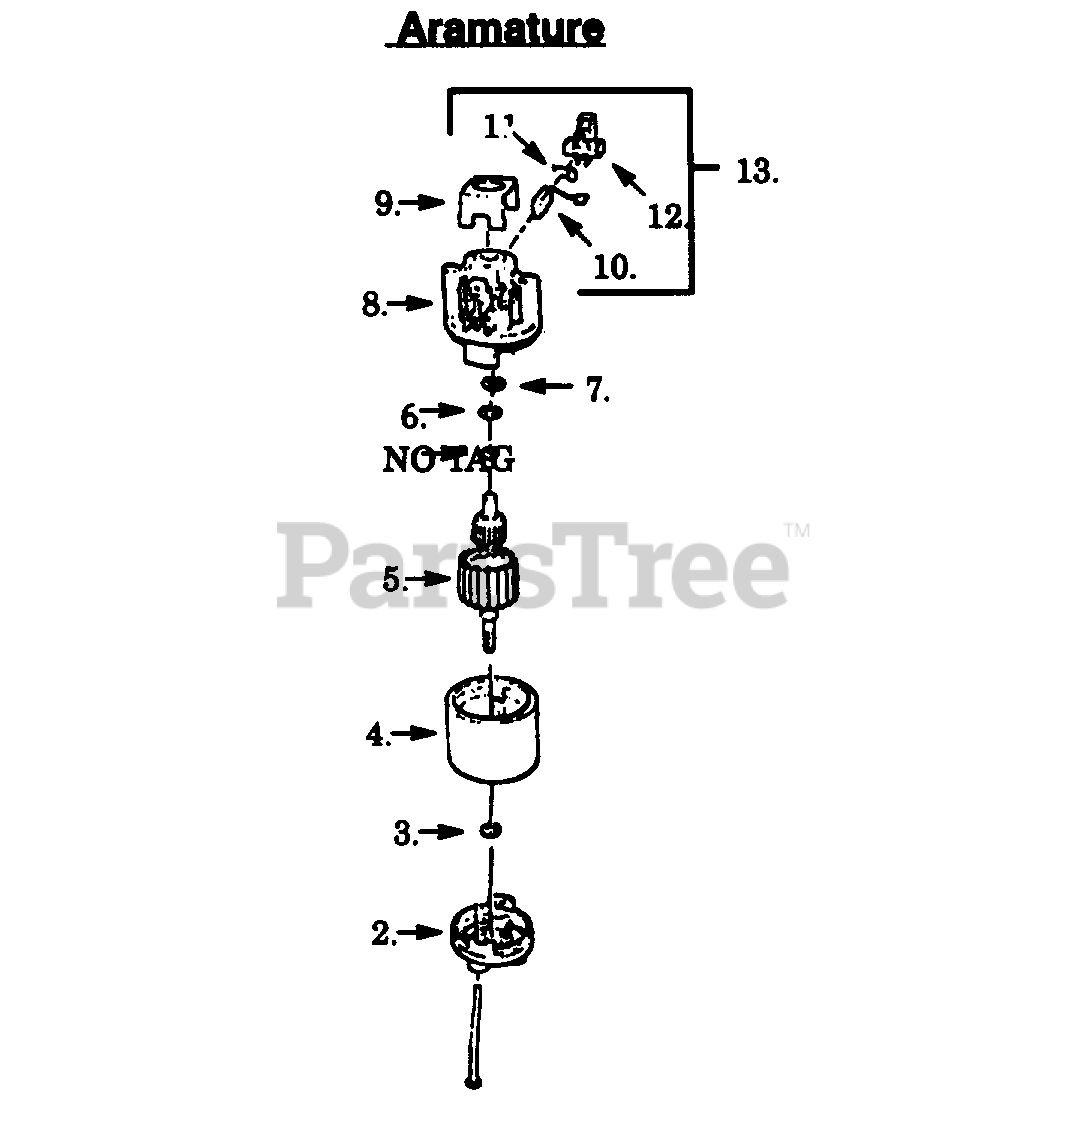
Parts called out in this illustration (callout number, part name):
2	Endbell Ass'y. (Drive)
4	Field Ass'y.
5	Armature Ass'y.
8	Endbell Ass'y. (Brush)
9	Insulator
10	Carbon Brush
11	Brush Spring
12	Brush Holder
13	Brush Kit (Incl. 10,11,12)
14	Retaining Ring
